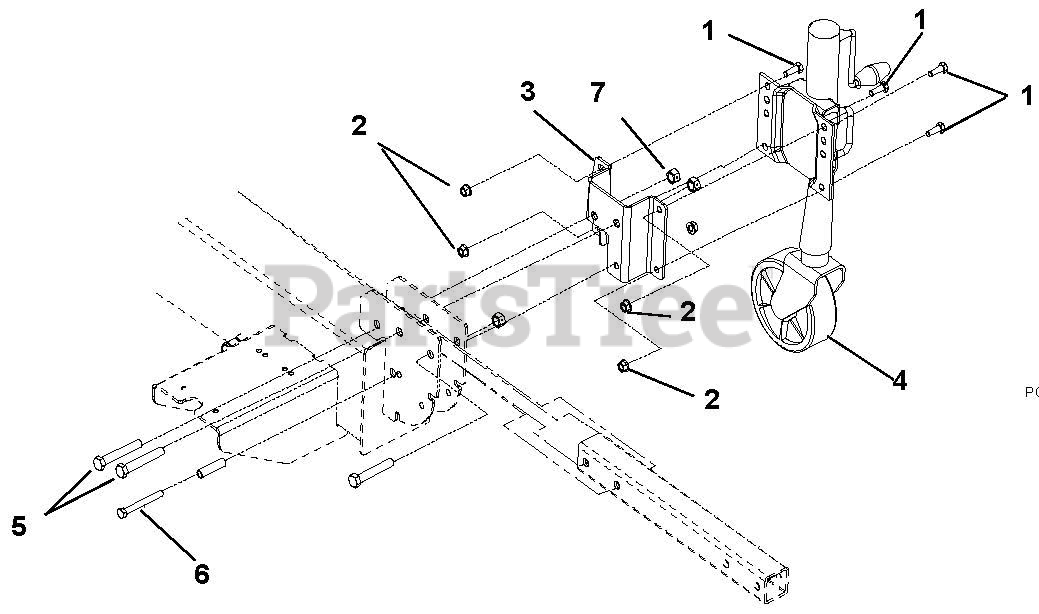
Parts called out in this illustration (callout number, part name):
1	@BLT-HEX .38-16X1.00 GR5 YWZC
2	@NUT-LK-TOP-FLG .38-16 YWZC
3	BRACKET, MOUNTING
4	STAND, JACK-W/WHEEL
5	@BLT-HEX .50-13X3.25 GR5 YWZC
6	@BLT-HEX .38-16X3.25 GR5 YWZC
7	@NUT-LK-CTR .50-13 YWZC
